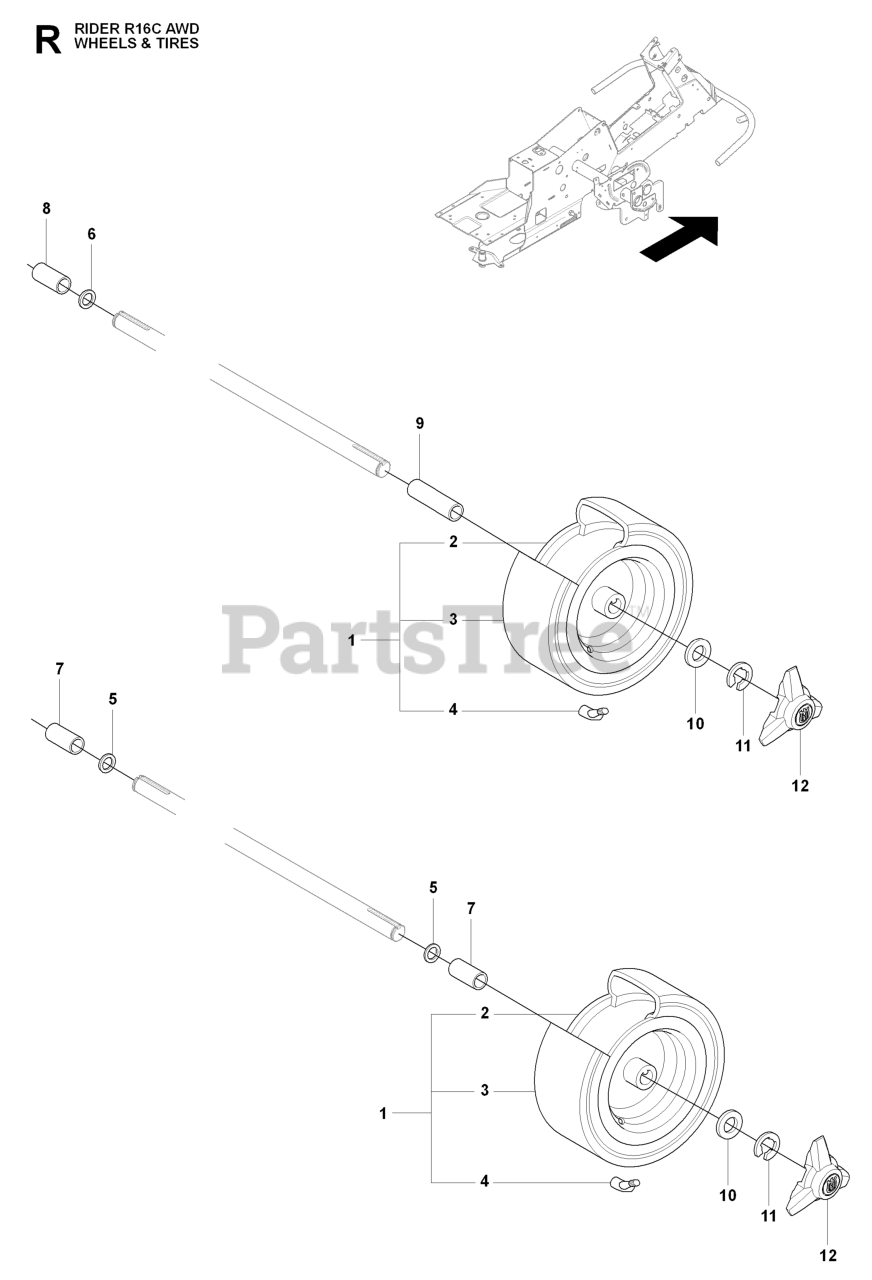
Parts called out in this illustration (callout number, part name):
1	WHEEL
2	RP RIM
7	SPACE SLEEVE
11	RETAINING RING
